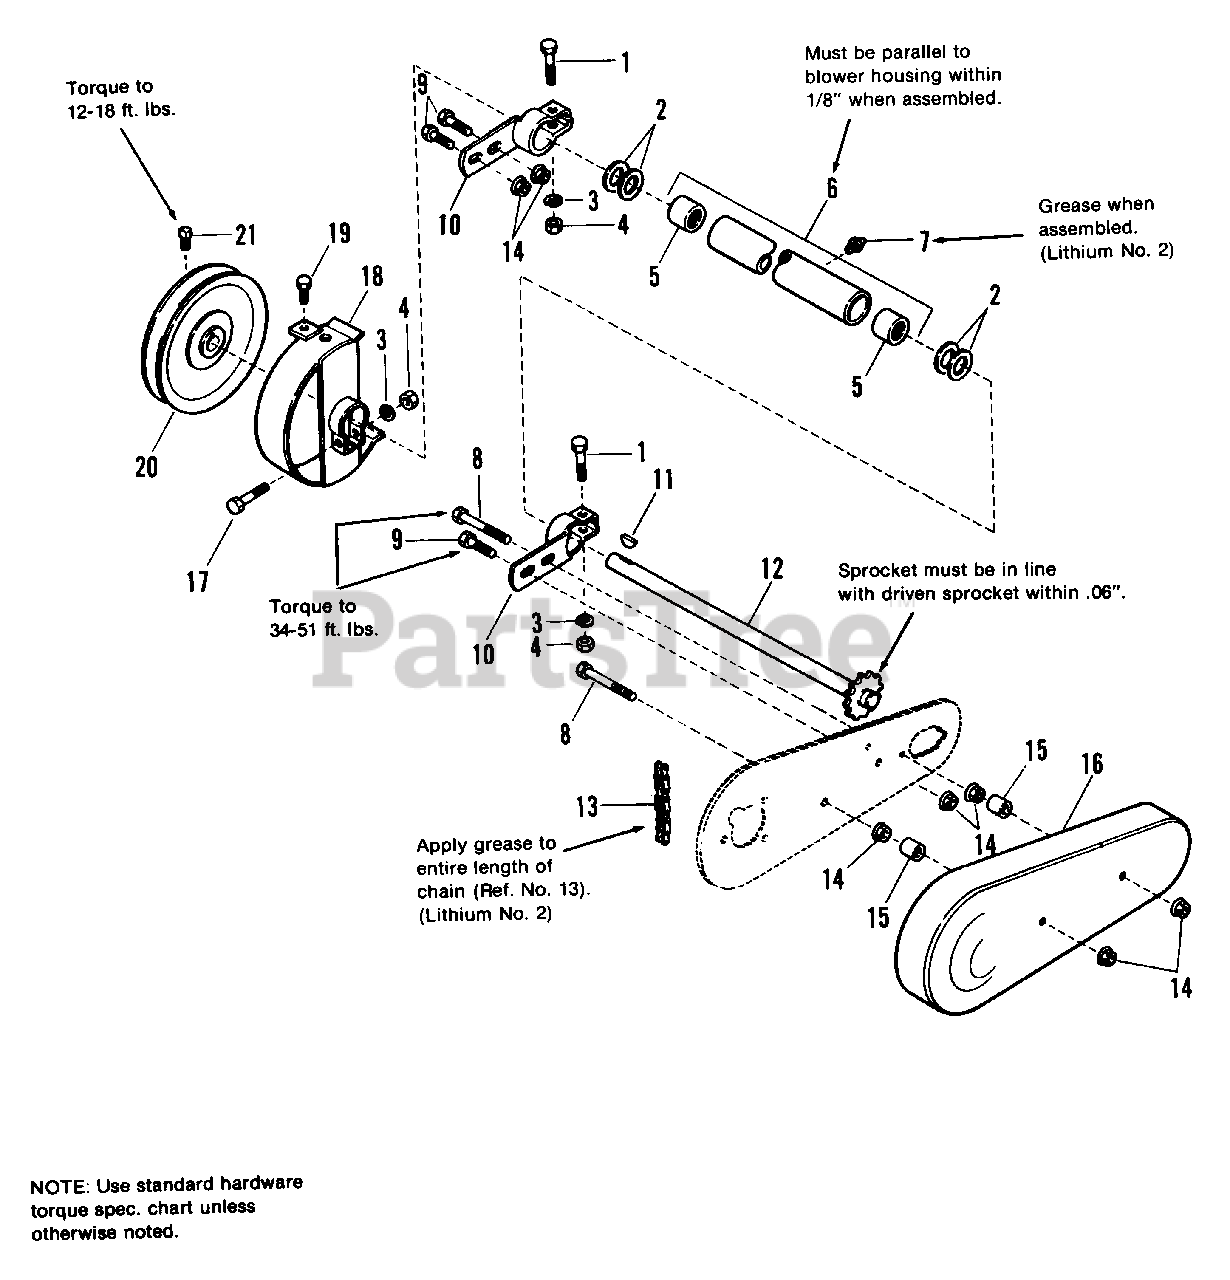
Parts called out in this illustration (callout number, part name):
1	CAPSCREW, Hex Hd., 5/16-18 x 1-3/4
3	LOCKWASHER, 5/16
4	NUT, 5/16
5	BEARING, Needle
6	BEARING & HOUSING ASSY. (1690403 Only)
6	BEARING & HOUSING ASSY. (1690513 Only)
7	FITTING, Grease
8	SCREW, Whizlock, 3/8-16 x 2-1/4
9	SCREW, Whizlock, 3/8-16 x 1
10	CLAMP, Housing
11	KEY, Woodruff, #9, 3/16 x 3/4
12	SHAFT ASSY. (1690403 Only)
12	SHAFT ASSY. (1690513 Only)
14	LOCKNUT, Flange, 3/8-16
16	GUARD, Chain
17	CAPSCREW, Hex Hd, 5/16-18 x 1-1/2
18	BELT GUARD ASSY.
19	SCREW, Tapping, 5/16-18 x 1/2
21	SETSCREW, Sq. Hd., 5/16-18 x 1/2
